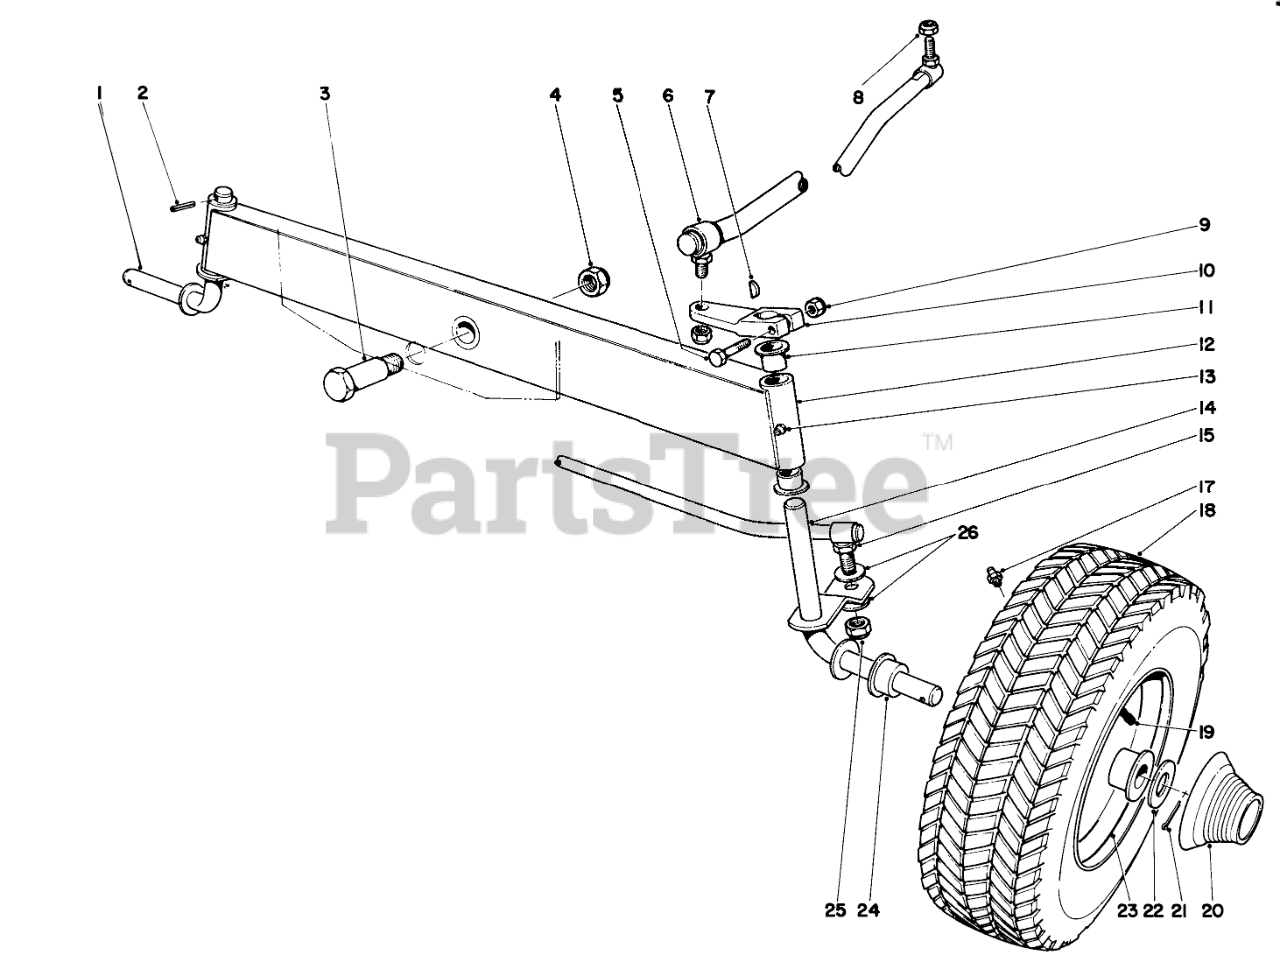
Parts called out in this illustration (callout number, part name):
1	Spindle
2	PIN-SPRING
3	Shoulder Bolt
5	SCREW-HH
6	Drag Link
7	KEY-WOODRUFF
8	Nut
10	Arm Drag Link
11	3/4IDX1LG FLANGE BSHG
12	Front Axle (Incl. Ref. No. 11)
13	GREASE FITTING
14	Spindle L.H.
15	Tie Rod
17	FITTING-GREASE
19	Valve Stem
20	FRONT HUB CAP
21	PIN-COTTER
22	Washer
23	Rim
24	Bushing
25	Nut
26	WASHER
